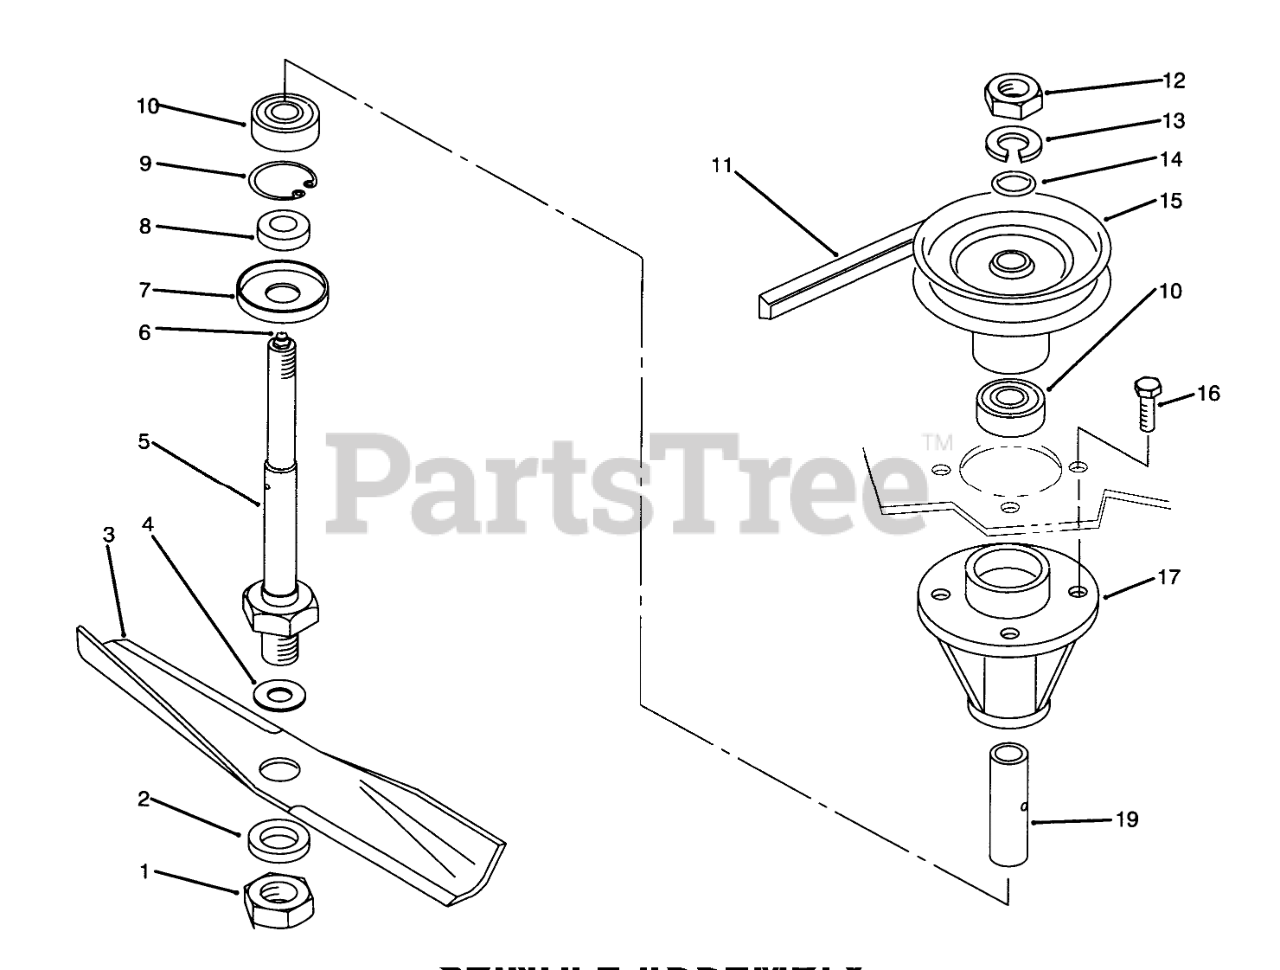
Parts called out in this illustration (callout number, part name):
1	NUT-JAM
2	WASHER-FLAT
3	14IN BLADE KIT
4	Washer
5	SHAFT-SPINDLE
6	FITTING-GREASE
7	CUP-SPINDLE
8	SPACER-BLADE
9	RING-RETAINING
10	BEARING-BALL
11	Belt
12	NUT-JAM
13	WASHER-LOCK
14	O RING
15	PULLEY
16	SCREW-HH
17	HOUSING-SPINDLE
